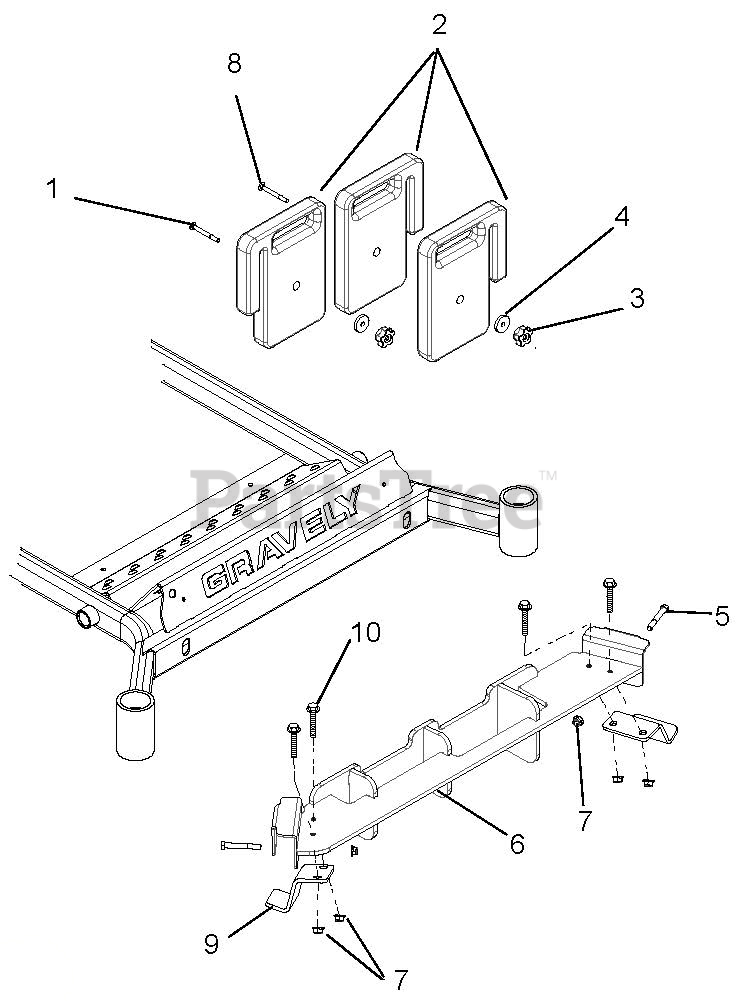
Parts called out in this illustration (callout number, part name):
1	Bolt, .312-18 x 4.5
2	Counterweight
3	Knob, Wing .312-18 UNC
4	Washer, Flat Steel .406 x 1.50 x .245
5	Bolt .38-16 x 2.75
6	Weldment, Weight Plate
7	Nut, .38-16 Nyloc Flange
8	Round Head Bolt, .31-18 x 3.00
9	Weight Plate Clamp
10	Hex Bolt, .38-16 x 1.25
